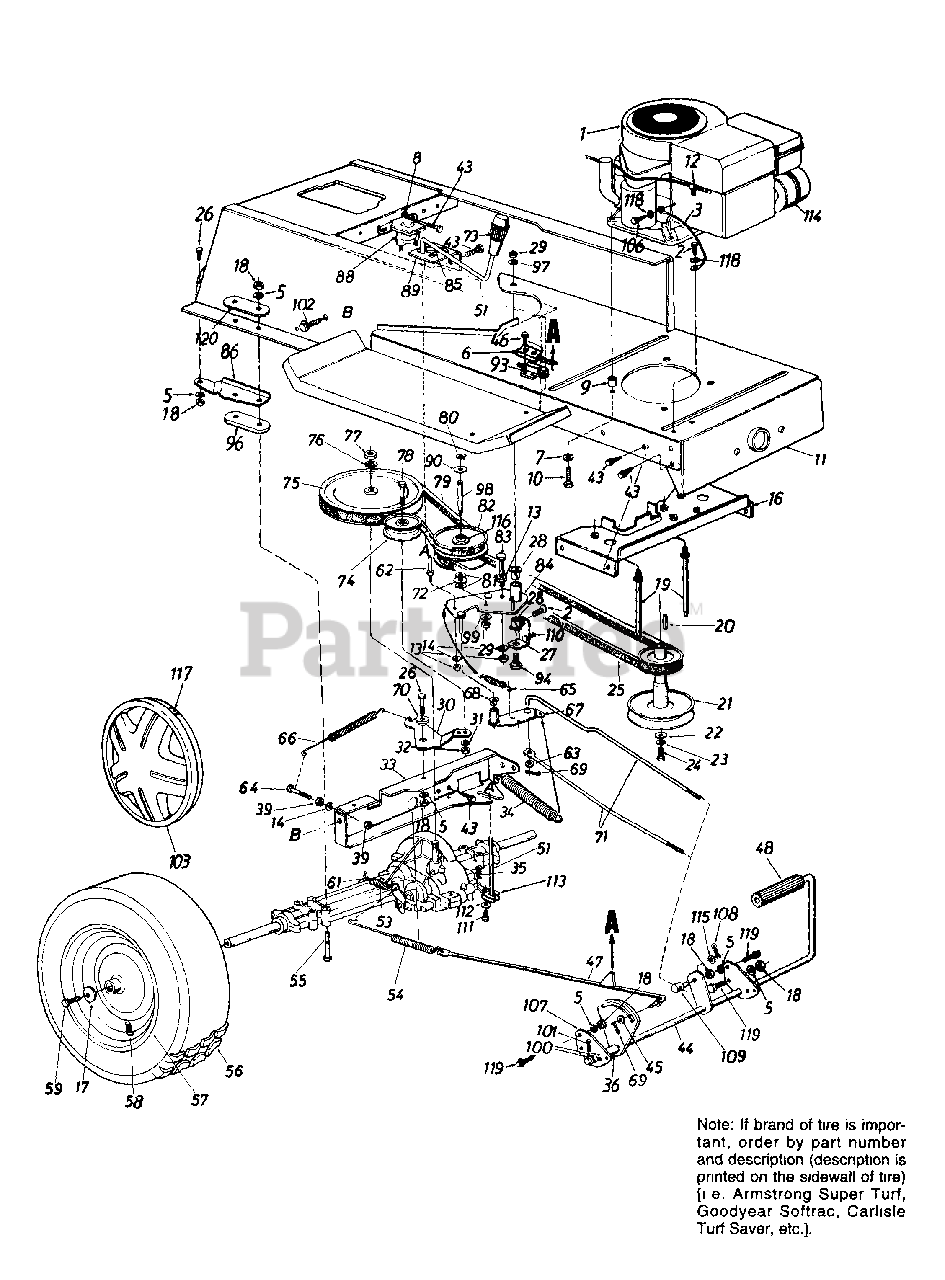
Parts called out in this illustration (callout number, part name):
1	Engine
2	Hex AB-Tap Scr. 5/16" x .75"
3	Electric Ground Wire
5	L-Wash. 5/16" I.D.
6	Switch Plate
7	Fl-Wash. .406" I.D. x 1.25"
8	Ext. L -Wash. 1/4" I.D.
9	Spacer
10	Hex Tap Scr. 3/8-16 x 1.5" L.g.
11	Lower Frame Ass'y.
12	Speed Clip
13	Hex Nut 1/4-20 Thd.
14	L-Wash. 1/4" I.D.
16	Belt Guard Brkt. Ass'y.
17	Bell-Wash. .345" I.D. x .88"
18	Hex Nut 5/16-18 Thd.
19	Belt Guard Stud 3.6" Lg.
20	Sq. Key 1/4" x 1/4" x 2.00"
21	Engine Pulley
22	Fl-Wash. 7/16" I.D. x 1.25"
23	L-Wash. 7/16" I.D.
24	Hex Bolt 7/16-20 x 1.50" Lg.
25	Variable-Speed Belt
26	Hex Bolt 5/16-18 x .75" Lg.
27	Bearing Shaft Bracket Ass'y.
28	Flanged Nyliner Brg. .63" I.D. x .6" Lg.
29	Hex Nut 3/8-24 Thd.
31	L-Wash. 3/8" I.D.
32	Hex Nut 3/8-24 Thd.
35	Inter. Cott-Pin
36	Spacer .63" I.D.
39	Hex Nut 1/4-28 Thd.
43	Hex S-Tap Scr. 1/4-20 x .5"
46	Truss Mach. B-Tap Scr. #10 x .5" Lg.
47	Brake Rod Ass'y.
48	Foot Pad
51	Shift Lever Ass'y.
53	Ext. Spring .38" O.D. x 2.5"
54	Ext. Spring 7.08" (Used w/20" Wheels w/o 46" Deck)
55	Hex Bolt 5/16-18 x 3.5" Lg. (Used w/18" Wheels or 46" Deck)
56	Wheel Ass'y. Comp.
57	Wheel Rim Only
58	Air Valve (Service Only)
59	Hex Bolt 5/16-24 x .75" Lg.
61	Brake Return Spring Anchor
62	Belt Guard Pin 1/4-20 Thd.
63	Fl-Wash. .34" I.D. x .68" O.D.
64	Hex Bolt 1/4-28 x 1.25" Lg.
65	Ext. Spring
66	Ext. Spring .62" O.D. x 6.12"
69	Cotter Pin 3/32" Dia.
70	Shoulder Spacer .27" Lg.
71	Speed Control Link
72	Truss Bearing .56 Dia. x 1.25"
73	Shift Knob
74	Fl-Idler Pulley 3.25" x .75"
75	"V"-Pulley (Used w/18" Wheels or 46" Deck)
76	Bell-Wash. .56" I.D. x 1.125"
77	Hex Jam Nut 9/16-18 Thd.
78	Hex Bolt 3/8-24 x 1.75" Lg.
79	Variable Speed Belt
80	Snap Ring .56" Dia.
81	Fl-Wash.
82	Variable Speed Pulley Ass'y. 5" O.D.
83	Hex Bolt 1/4-20 x 3.5" Lg.
90	Teflon Washer .565" I.D.
93	Safety Switch (Clutch)
94	Shld. Bolt 3/8-24 x 3.12" Lg.
96	Transaxle Spacer (Used w/18" Wheels or 46" Deck)
97	Bell-Wash. .38" I.D. x .88"
98	Shaft .56" Dia. x 3.875" Lg.
99	Bell-Wash. .39" I.D. x 1.12"
100	Fl-Wash. .64" I.D. x .94"
101	Cotter Pin 1/8" Dia. x 1.25"
102	Hex Wash. Hd. Scr. 5/16-18 x .62" Lg.
103	Hub Cap (Gray)
106	Pan Hd. Mach. Scr. 5/16-18 x .75" Lg.
109	Ferrule
110	Hex Bolt 5/16-18 x 1.0" Lg.- (Gr. 5)
111	Hex Bolt 1/4-28 x .50" Lg.
112	Bell-Wash. .265" I.D. x .75"
113	Shift Lever Link Ass'y.
114	Muffler (Refer to Style Sheet)
115	Fl-Wash. .385" I.D. x .62"
116	Needle Brgs.
117	Spring Clip (Used w/Ref. #103)
118	External L-Wash. 5/16" I.D.
119	Hex TT-Tap Scr. 5/16-18 x .75"
